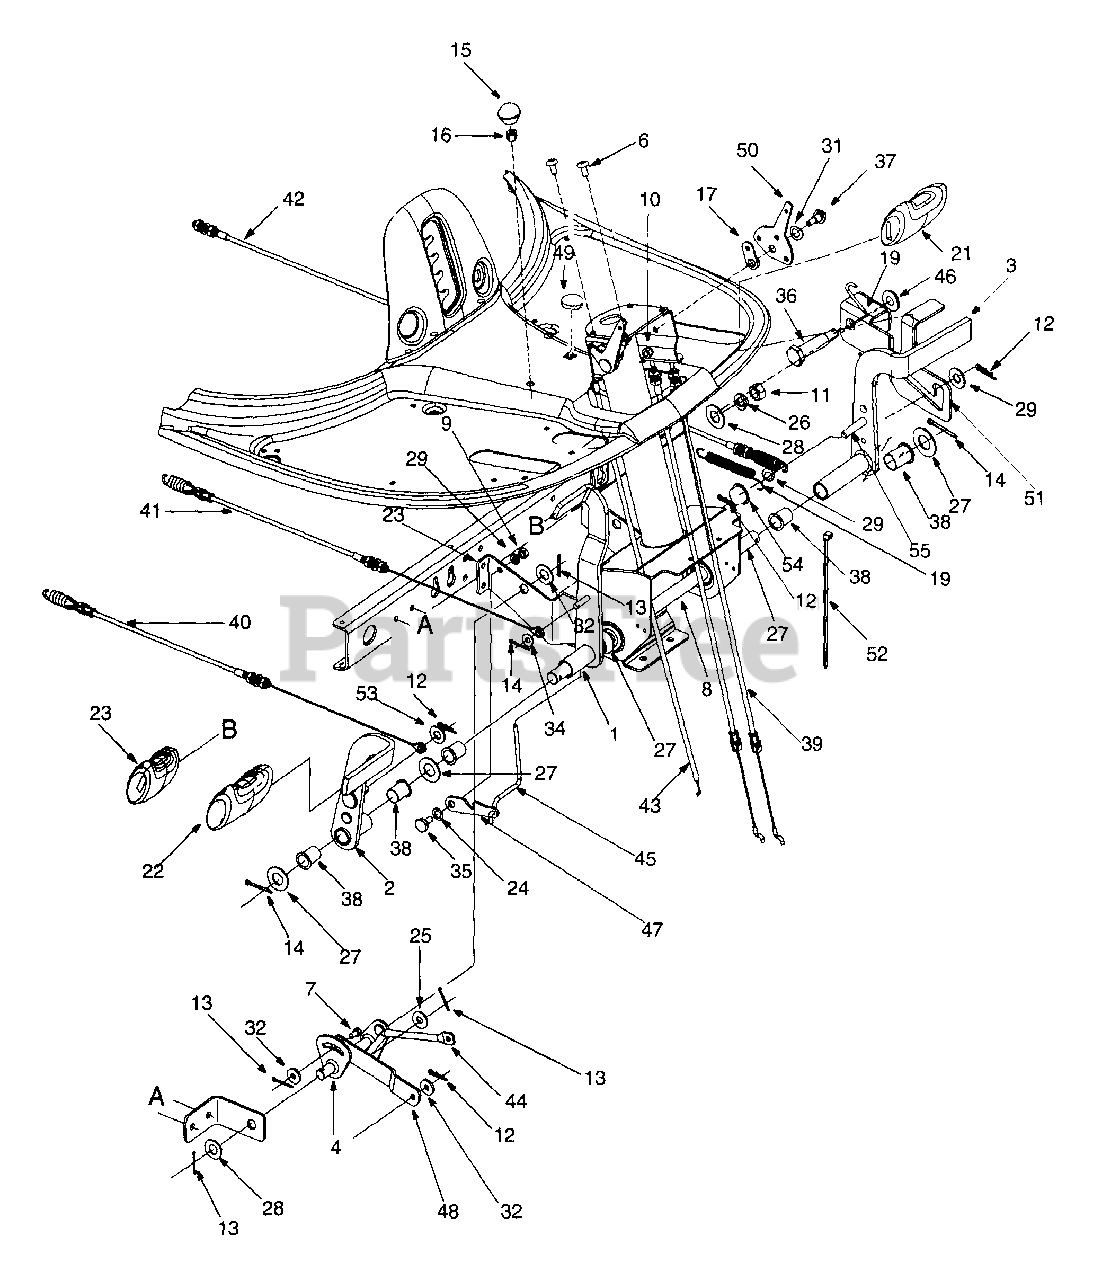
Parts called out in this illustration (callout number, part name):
6	Ab Screw 1/4-14 X .625
7	Clevis Pin
8	Shaft
9	Hex Nut 1/4-20
10	Lock Nut 1/4-20
11	Hex Nut 3/8-16
12	Internal Cotter Pin
13	Cotter Pin
14	Cotter Pin
15	Ball Knob
16	Snap-on Bushing
17	Stop Lever
19	Torsion Spring
21	Deck Pad
22	Drive Pad
23	Brake Pad
24	Flat Washer 3/8 X .620 X .033
25	5/16 Washer
26	Lock Washer
27	Flat Washer
28	Flat Washer .510 X 1.00 X .060
29	N Flat Washer .406 X 1.25 X .10
31	Spring Washer .45 X .74 X .035
32	Flat Washer
34	Flat Washer .271 X .630 X .065
35	Shoulder Screw .375 Dia X .18
36	Shoulder Screw
37	Shoulder Screw .375 X .380 X 1/4-20
38	Flange Bearing
39	Shift Cable
40	Variable Drive Cable
41	Brake Cable
42	Deck Cable
43	Throttle Choke Cable: 67"
44	Brake Rod
45	Brake Lock Out Rod
46	Shoulder Spacer
50	Shift Lever
53	Flat washer .406 I.D. x .875 O.D x .0459
54	Push Cap
55	Weld Pin
